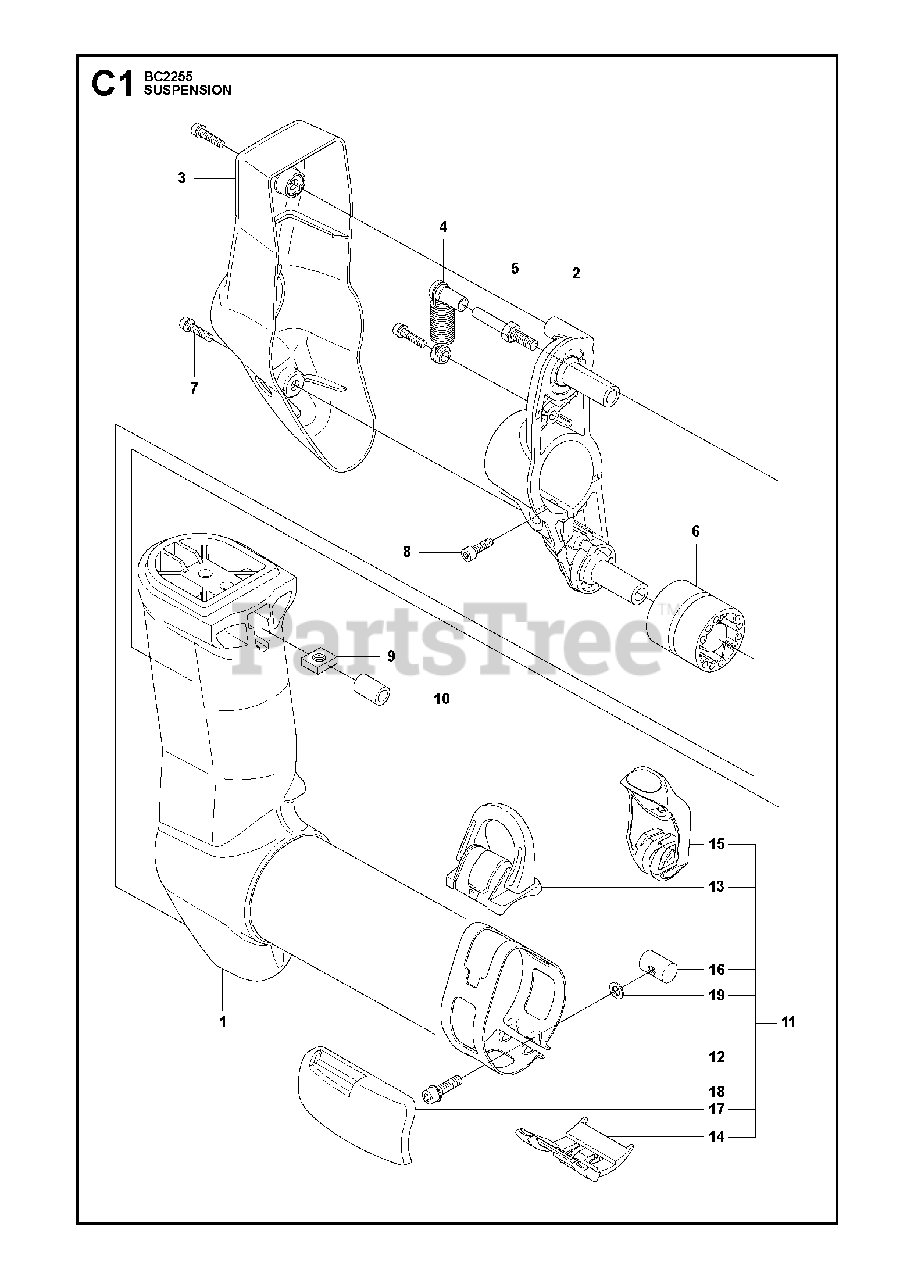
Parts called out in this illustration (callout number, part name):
5	PARALLEL PIN
6	ANTIVIBE ELEMENT
7	SCREW IHSCFM
12	BAND
13	LOOP
16	NUT
18	SCREW
19	WASHER 5.3X12
